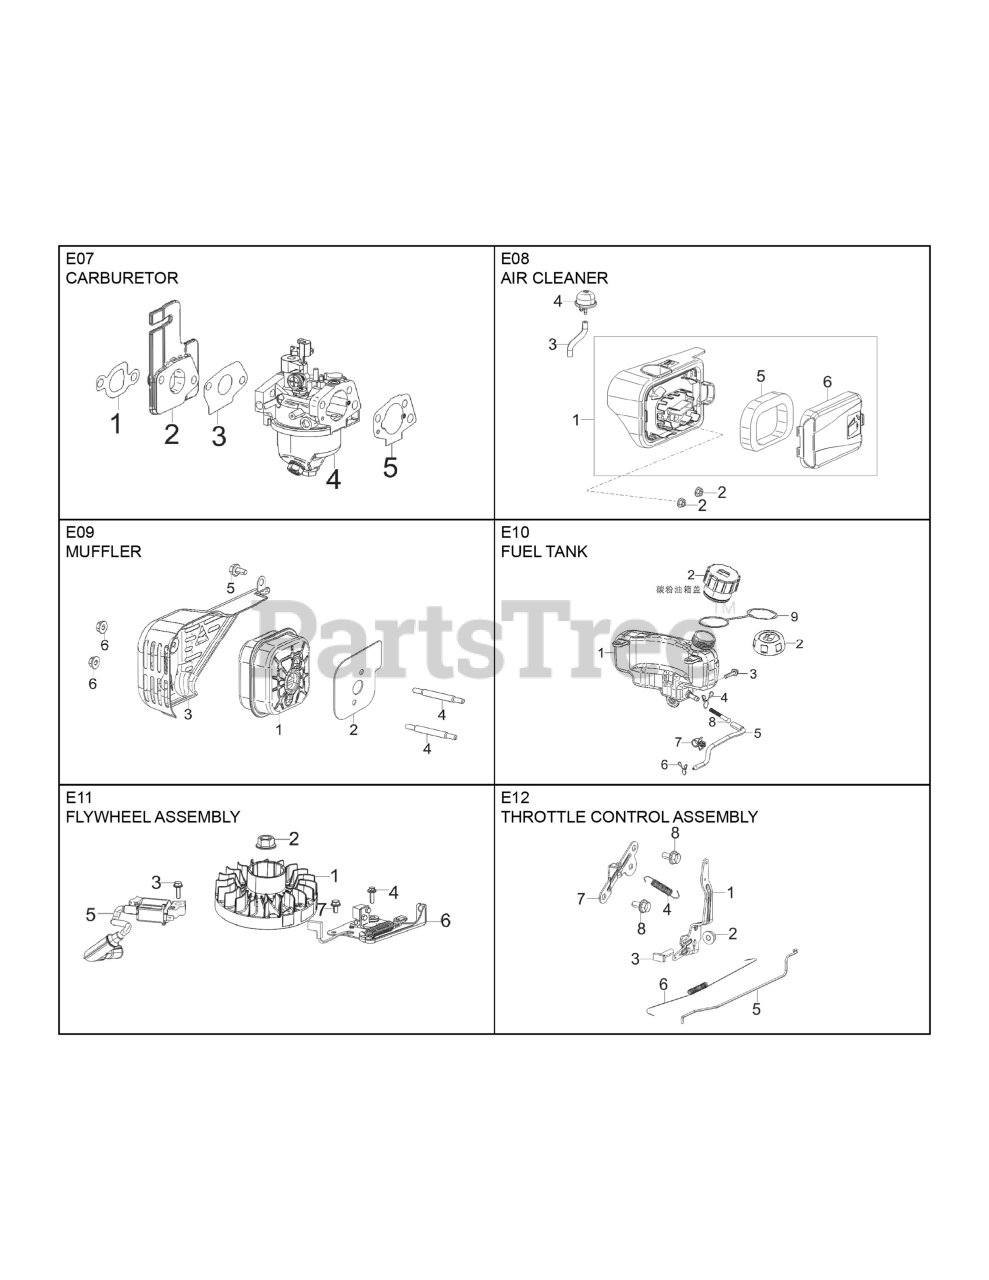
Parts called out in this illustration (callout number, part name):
E11	FLYWHEEL ASSY RVM120 FLYWHEEL
E10	FUEL TANK KIT
E09	MUFFLER KIT RVM120 MUFFLER KIT
E07	CARBURETOR KIT
E08	AIR FILTER ASSY RVM120 AIR CLE
E12	THROTTLE ASSY RVM120 THROTTLE
